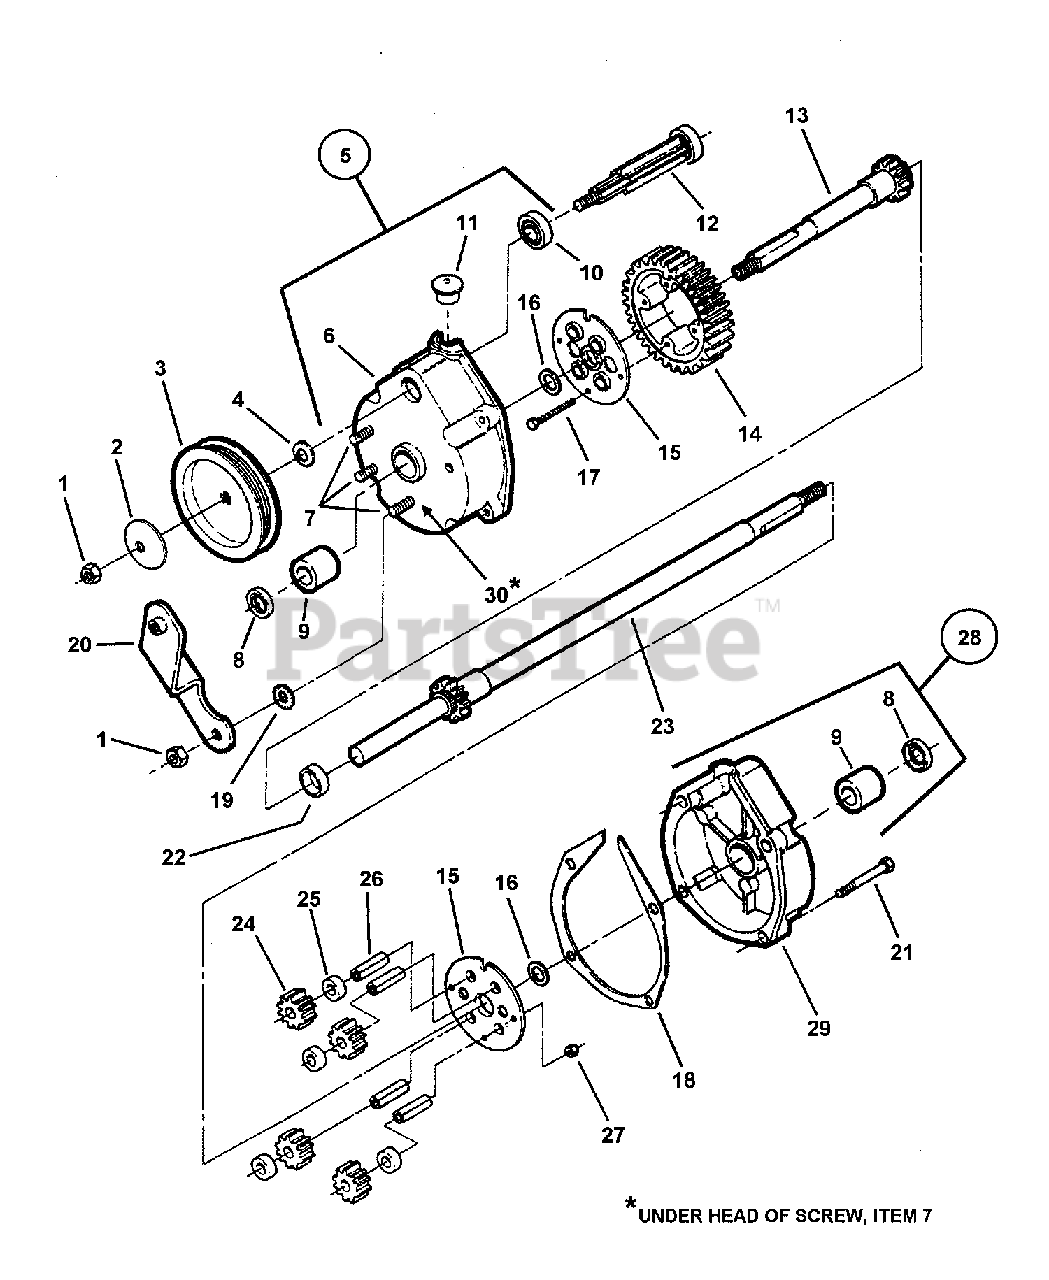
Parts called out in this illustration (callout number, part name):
1	NUT, 5/16-24 Hex Lock, GR C
2	WASHER, 5/16" I.D. Cone
3	PULLEY, Poly-Vee Belt
4	WASHER, Spring
5	ASSEMBLY, Housing, Right (Incl. items 6 thru 10)
6	HOUSING, Right Side
7	SCREW, 5/16-24 x 1-1/8" Rib Neck, GR5
8	SEAL, 5/8" Internal Dia.
9	BEARING, Tapered- (Differential Housing)
10	BEARING, Ball
11	PLUG, Housing
12	GEAR, Input
13	AXLE, Short
14	GEAR, Differential (46 tooth)
15	PLATE, 46T Gear
16	WASHER, Thrust, 3/4" I.D.
17	SCREW, #10-32 x 1-1/2" Hex Head Cap GR5
18	GASKET, Housing
19	WASHER, 5/16" Internal/External Tooth Lock
20	BRACKET, Differential
21	SCREW, 1/4-20 x 1" Hex Washer Self-Tap
22	SPACER, Axle Gear
23	AXLE, Long
24	GEAR, Pinion (12 tooth)
25	SPACER, Pinion Gear
26	SHAFT, Pinion
27	NUT, #10-32 Hex Nyloc
28	ASSEMBLY, Left Housing (Includes items 8, 9 & 29)
29	HOUSING, Left
30	GASKET, 5/8" O. D.
